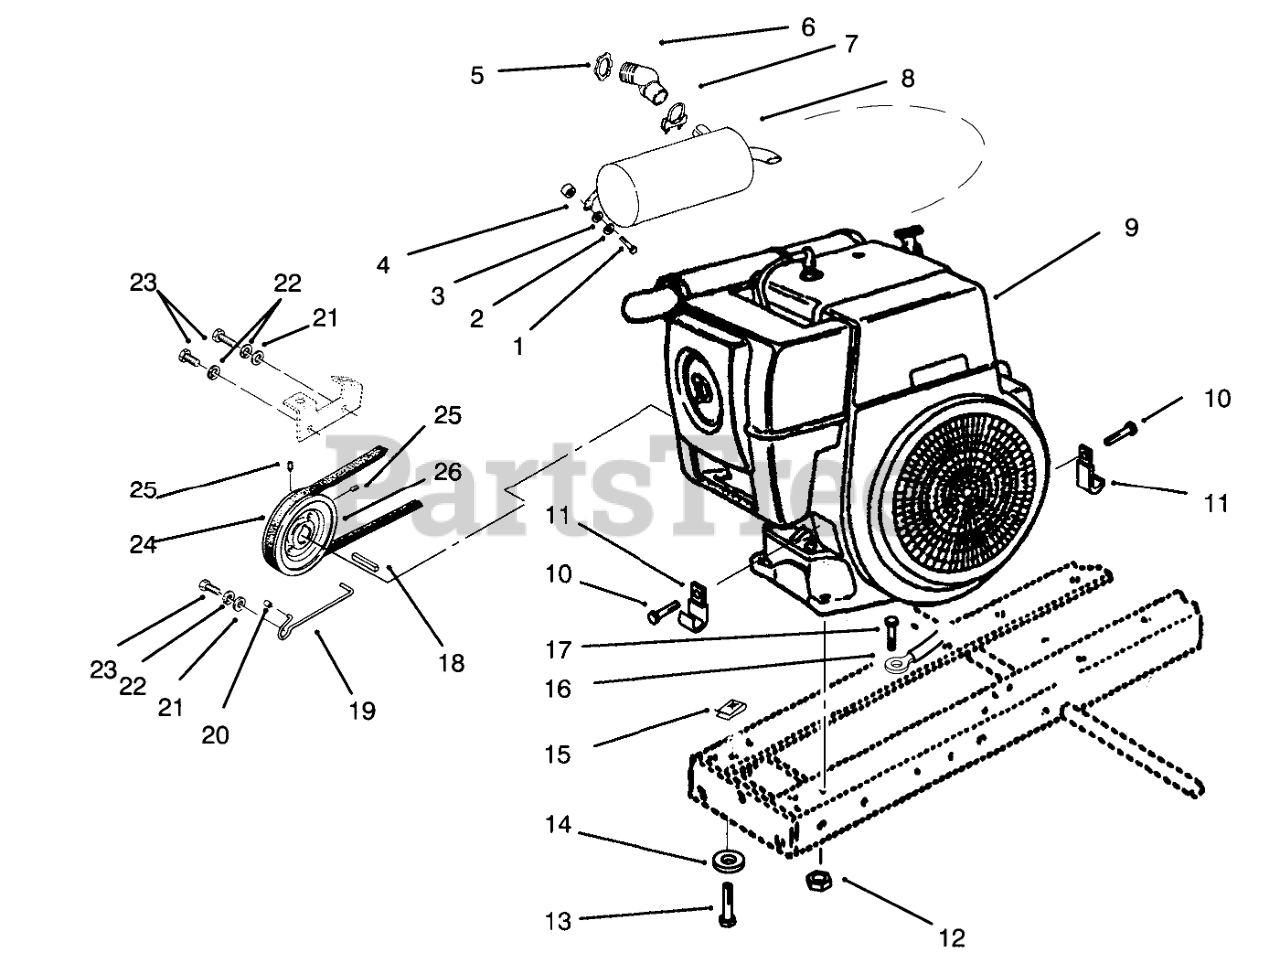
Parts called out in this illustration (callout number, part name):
1	SCREW-HH
2	WASHER-LOCK
3	WASHER-PLAIN
4	SPACER
5	Nut-Lock
6	Elbow
7	CLAMP-1 1/2
8	Muffler
9	Engine-14HP
10	Screw (Engine) Ref
11	CLIP
12	NUT-LOCK, NI
13	SCREW-HH
14	WASHER-LOCK
15	SPEED CLIP
16	WIRE GROUND
17	SCREW-HH
19	GUIDE BELT
21	WASHER-FLAT
22	WASHER-LOCK
23	SCREW-HH
24	V-BELT TRANS DRIVE
25	SCREW-SET, HSH
26	PULLEY
